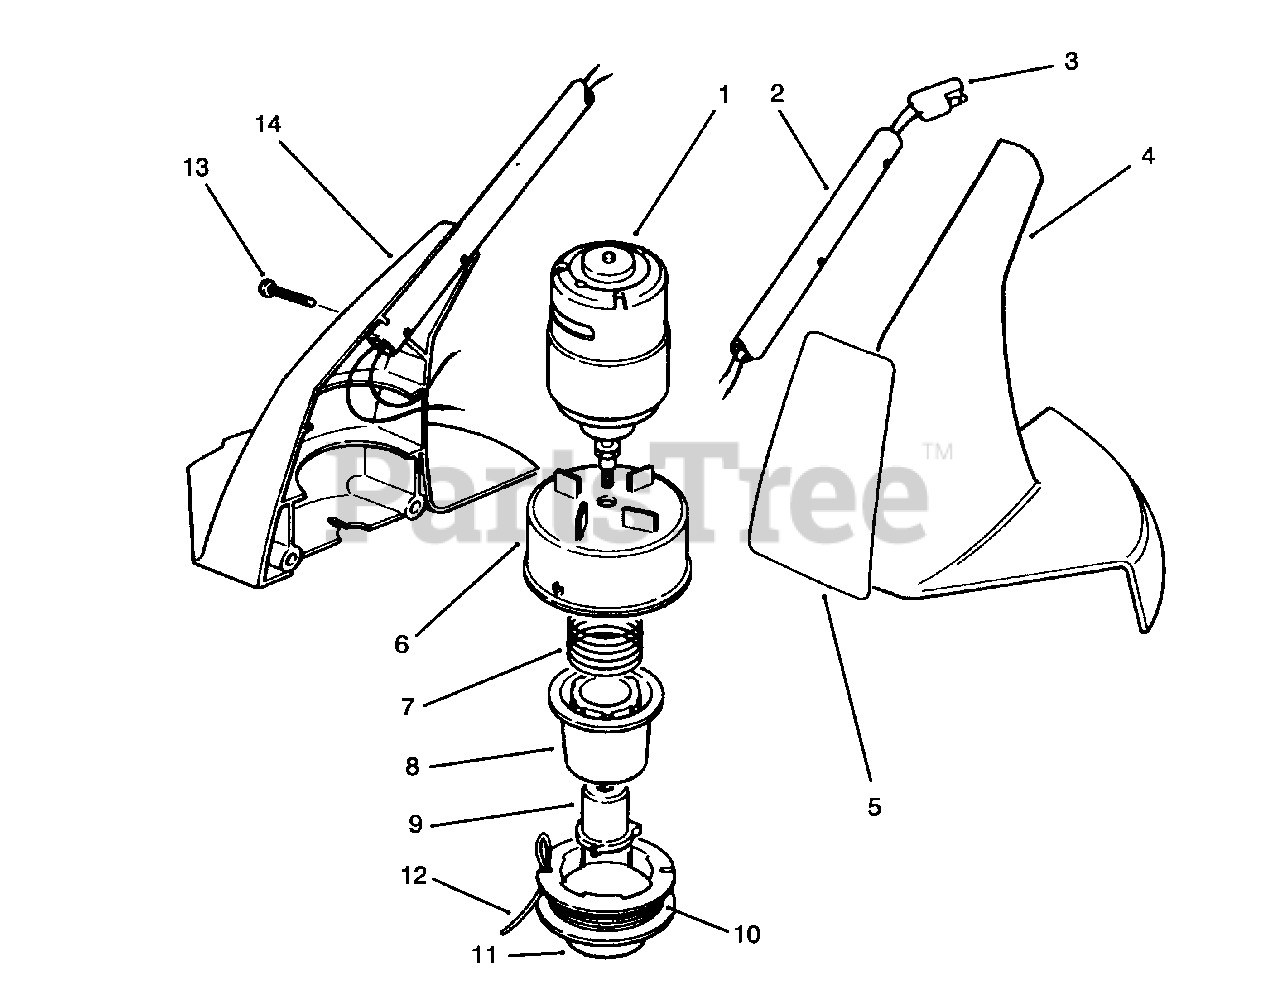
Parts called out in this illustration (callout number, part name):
1	Motor
2	Extension-Handle
3	Wiring Harness-Lower
4	Housing-Motor L.H.
5	Decal-Cordless
6	Drum w/Eyelet
10	Line-Cutting 12'.050 Dia. Prewound Spool
11	Spool-Empty
12	Line-Cutting 30'.050 Dia. in Coil
14	Housing-Motor R.H.
